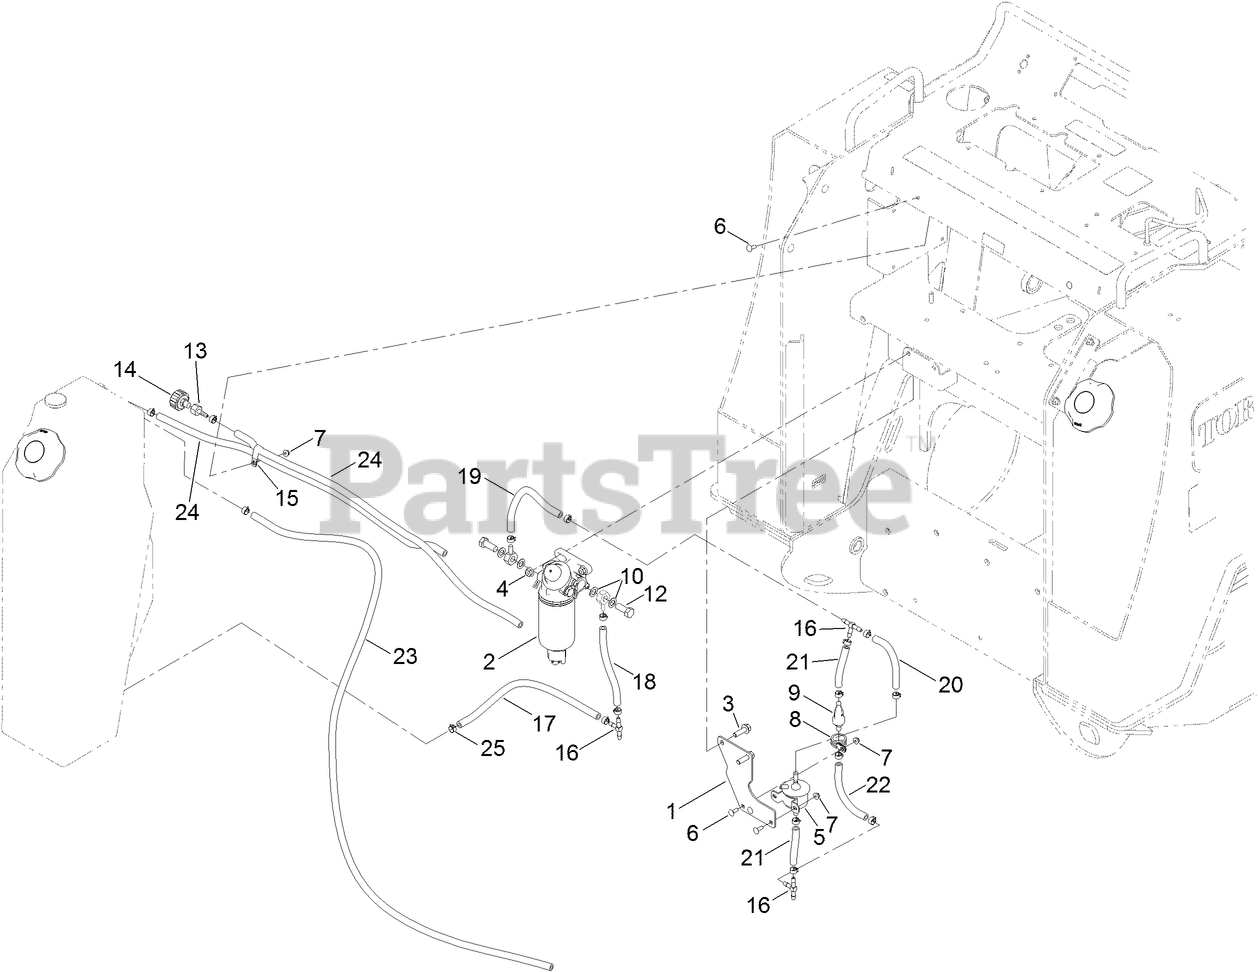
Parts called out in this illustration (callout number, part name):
1	BRACKET-FUEL PUMP
2	FILTER-SEPERATOR, WATER
3	SCREW-HHF
4	NUT-HF, NI
5	PUMP-FUEL
6	BOLT-CARR
7	NUT-HF
8	R-CLAMP
9	VALVE-BYPASS
10	O-RING
12	SCREW-ADAPTER
13	FITTING-STRAIGHT
14	BREATHER
15	CLAMP-R, DOUBLE TUBE
16	FITTING-TEE, BARBED
17	HOSE-FUEL
18	HOSE-FUEL
19	HOSE-FUEL
20	HOSE-FUEL
21	HOSE-FUEL
22	HOSE-FUEL
23	HOSE-FUEL
24	HOSE-FUEL
25	CLAMP-HOSE
